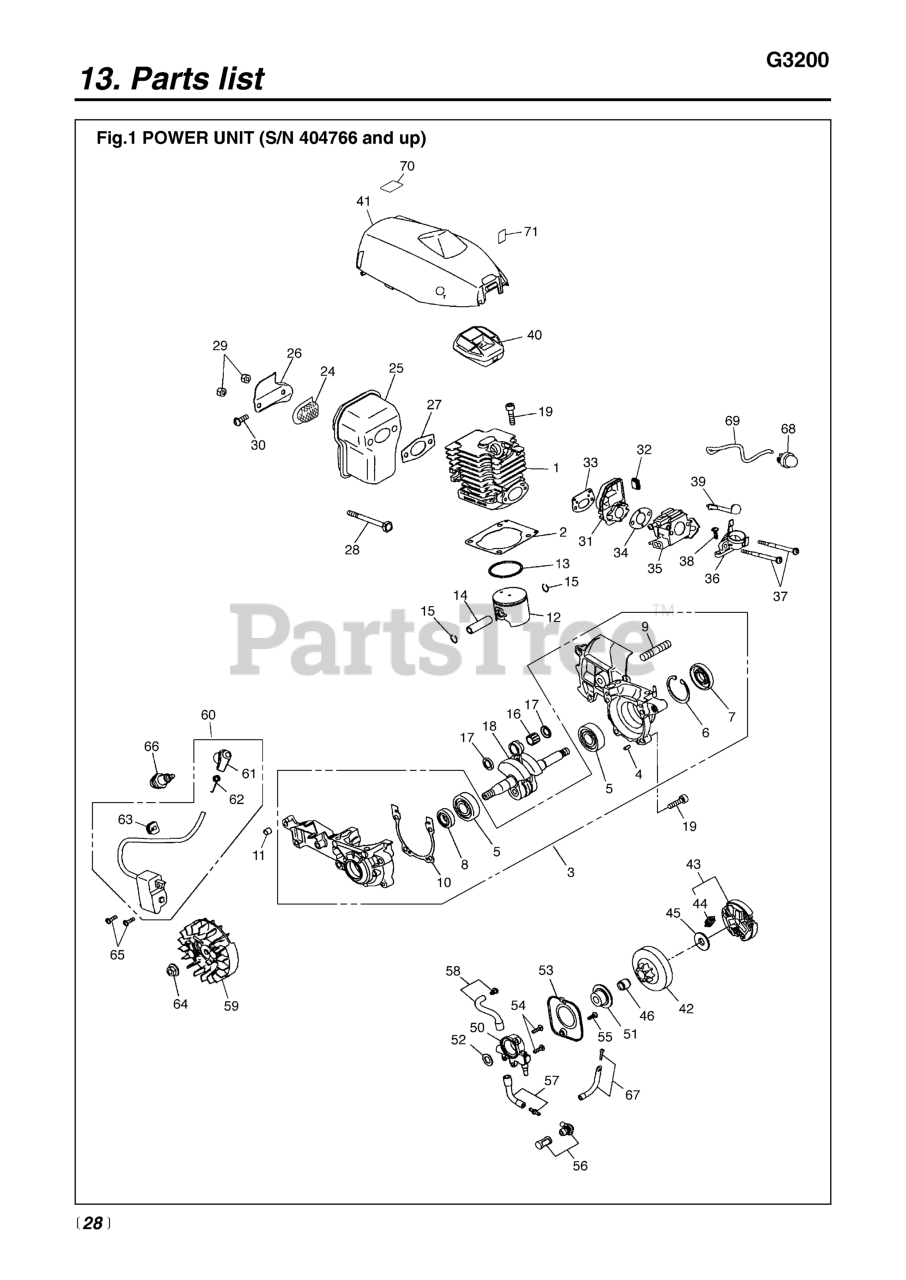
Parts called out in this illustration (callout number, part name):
3	CASE ASSY
4	PIN
6	RING, SNAP, M32 x 1.2
7	SEAL, OIL (RPLS 1100-21210)
8	SEAL
9	STUD (RPLS 0205-50825)
12	PISTON
15	RING, SNAP
16	BEARING
17	WASHER (RPLS 3310-41341)
18	SHAFT COMP
19	BOLT (RPLS 2850-14220)
27	GASKET, MUFFLER
29	NUT, MUFFLER (RPLS 3356-15230
30	SCREW
31	INSULATOR
34	GASKET
36	MANIFOLD
37	BOLT
38	SCREW
40	CLEANER
42	DRUM
44	SPRING
46	BEARING
50	PUMP, OIL
51	WORM GEAR
52	WASHER
54	SCREW
55	SCREW
56	FILTER COMPLETE
57	PIPE IN COMP
58	PIPE OUT COMP
59	ROTOR COMP
60	COIL ASSY
61	CAP, PLUG
62	SPRING PLUG (RPLS 3310-71320)
63	GROMMET
65	SCREW
66	PLUG, SPARK, RCJ7Y
67	PIPE COMPLETE
68	PUMP ASSEMBLY
70	LABEL, CAUTION
71	LABEL, CHOKE
